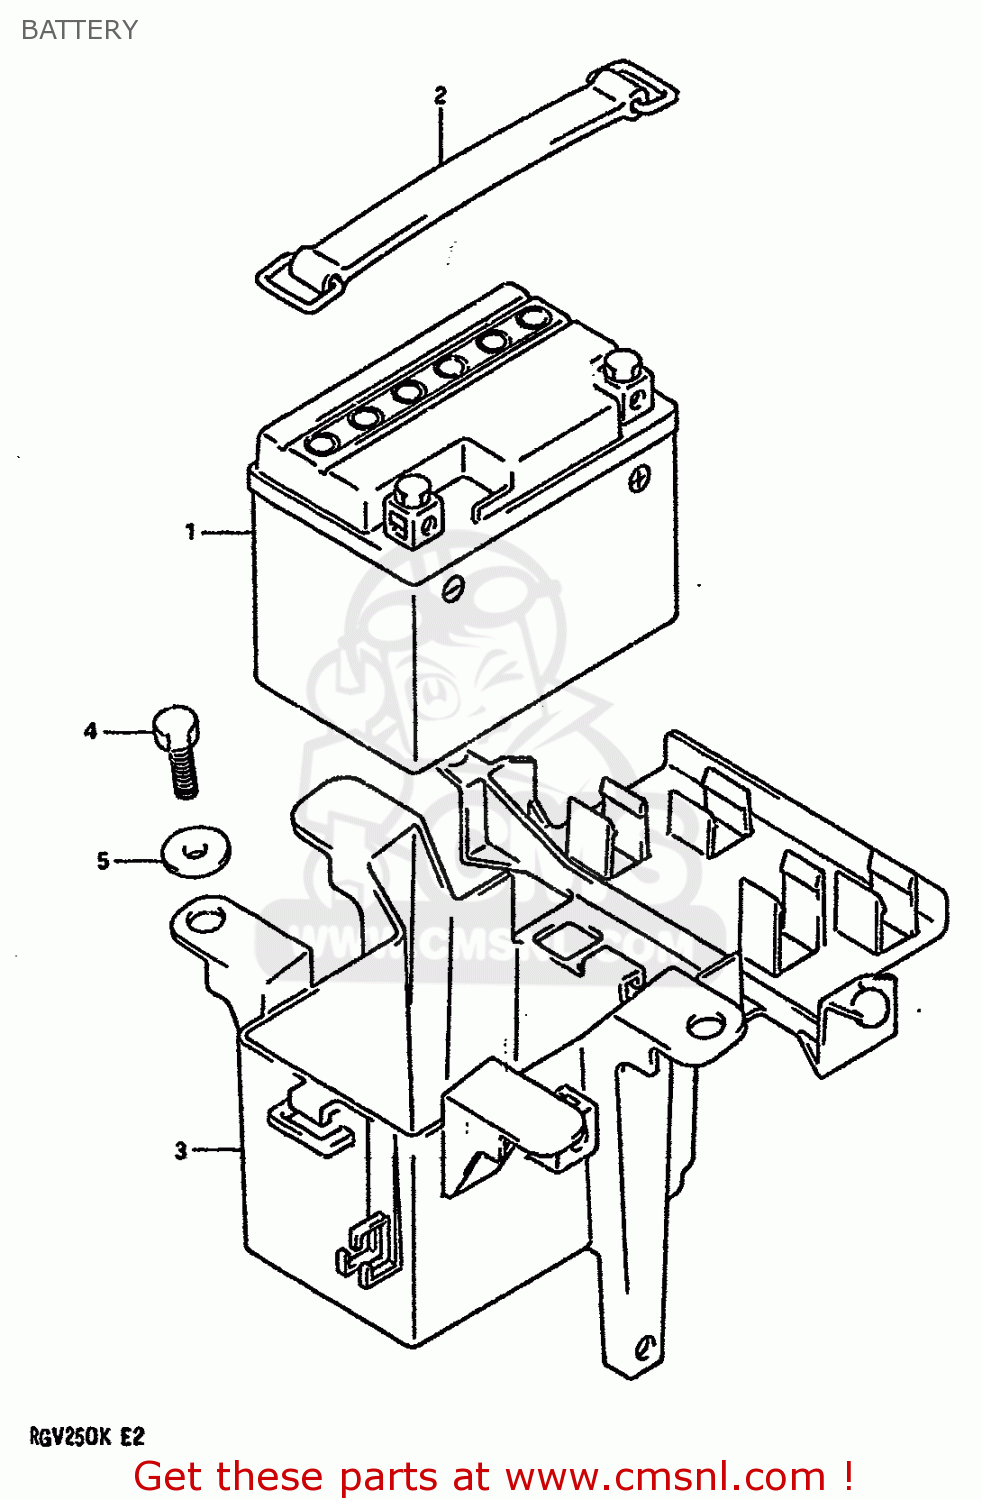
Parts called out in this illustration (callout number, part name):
1	BATTERY ASSY (12V3AH)
2	BAND,BATTERY
3	HOLDER,BATTERY
4	BOLT
5	WASHER
